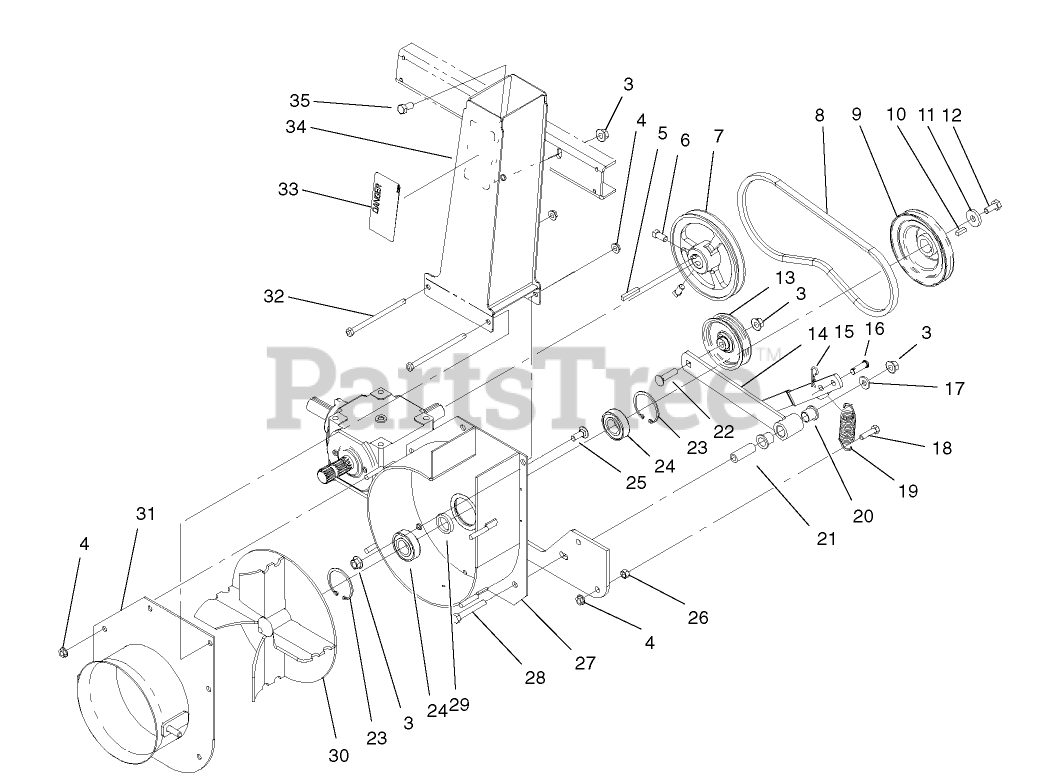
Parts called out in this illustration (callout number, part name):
3	NUT-HF
4	NUT-HF
5	KEY-SQUARE
6	SCREW-SET, SQH
7	PULLEY-GEARBOX
8	V-BELT
9	Pulley-Impeller
10	KEY-SQUARE
11	WASHER-THRUST, PLAIN
12	SCREW-HH
13	PULLEY-IDLER
14	IDLER ARM ASM
15	PIN-HAIR
16	PIN-CLEVIS
17	WASHER-FLAT
18	SCREW-HH
19	SPRING-EXTENSION
20	BUSHING-FLANGE
21	SPACER
22	SCREW-CARR
23	RING-SNAP
24	BEARING-BALL
25	BOLT-CARR
26	NUT-HEX
27	HOUSING ASM
28	SCREW-HH
29	SPACER-BEARING
30	IMPELLER ASM
31	COVER ASM
32	SCREW-HH
33	DECAL-DANGER
34	IMPELLER CHUTE ASM
35	SCREW-HH
